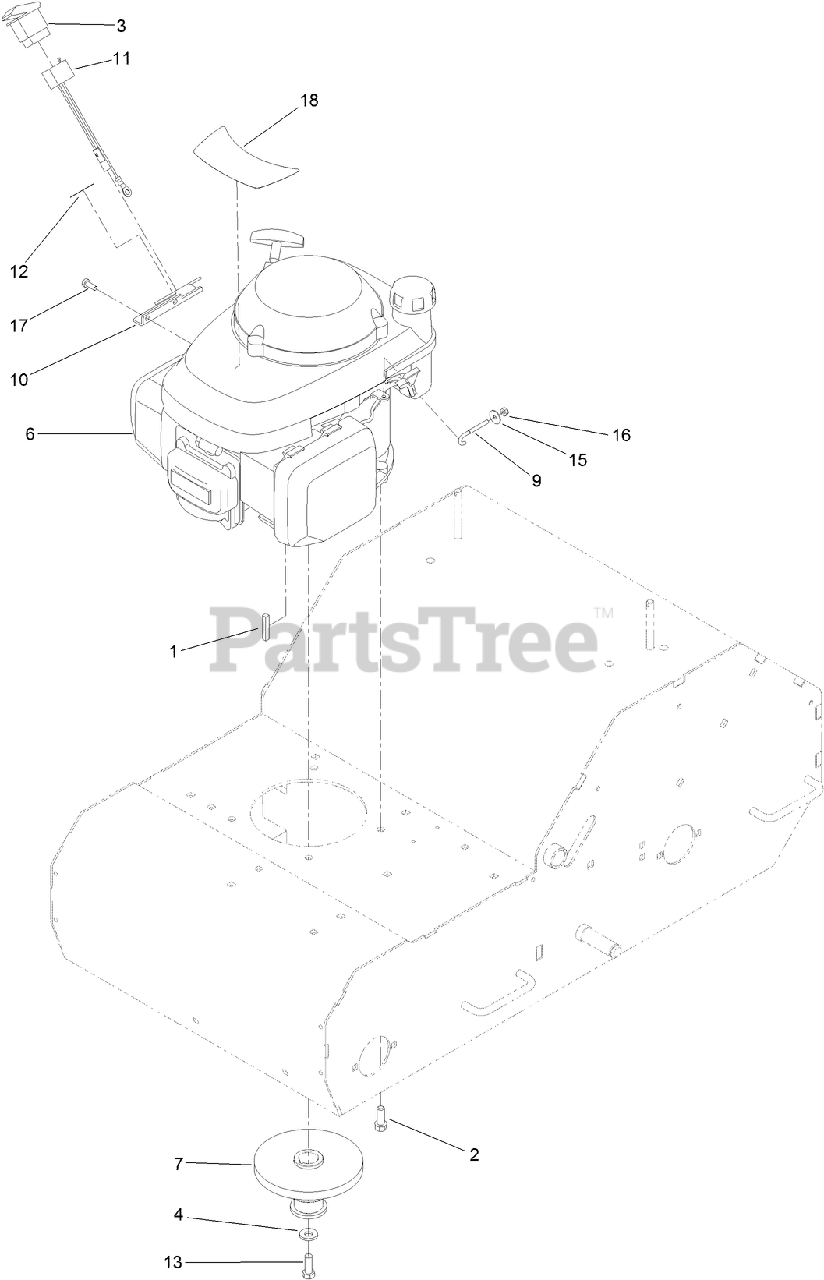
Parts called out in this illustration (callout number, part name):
1	KEY-SQUARE
2	SCREW-TAPTITE
3	SWITCH
4	WASHER-BELLEVILLE
6	ENGINE-HONDA, GSV190LA A3T
7	PULLEY-ENGINE, DOUBLE
9	HOOK-OVERRIDE
10	BRACKET-SWITCH
11	HARNESS-WIRE
12	DECAL-ON/OFF
13	SCREW-HH
15	WASHER-FLAT
16	NUT-LOCK, NI
17	SCREW-HH
18	DECAL-ENGINE
